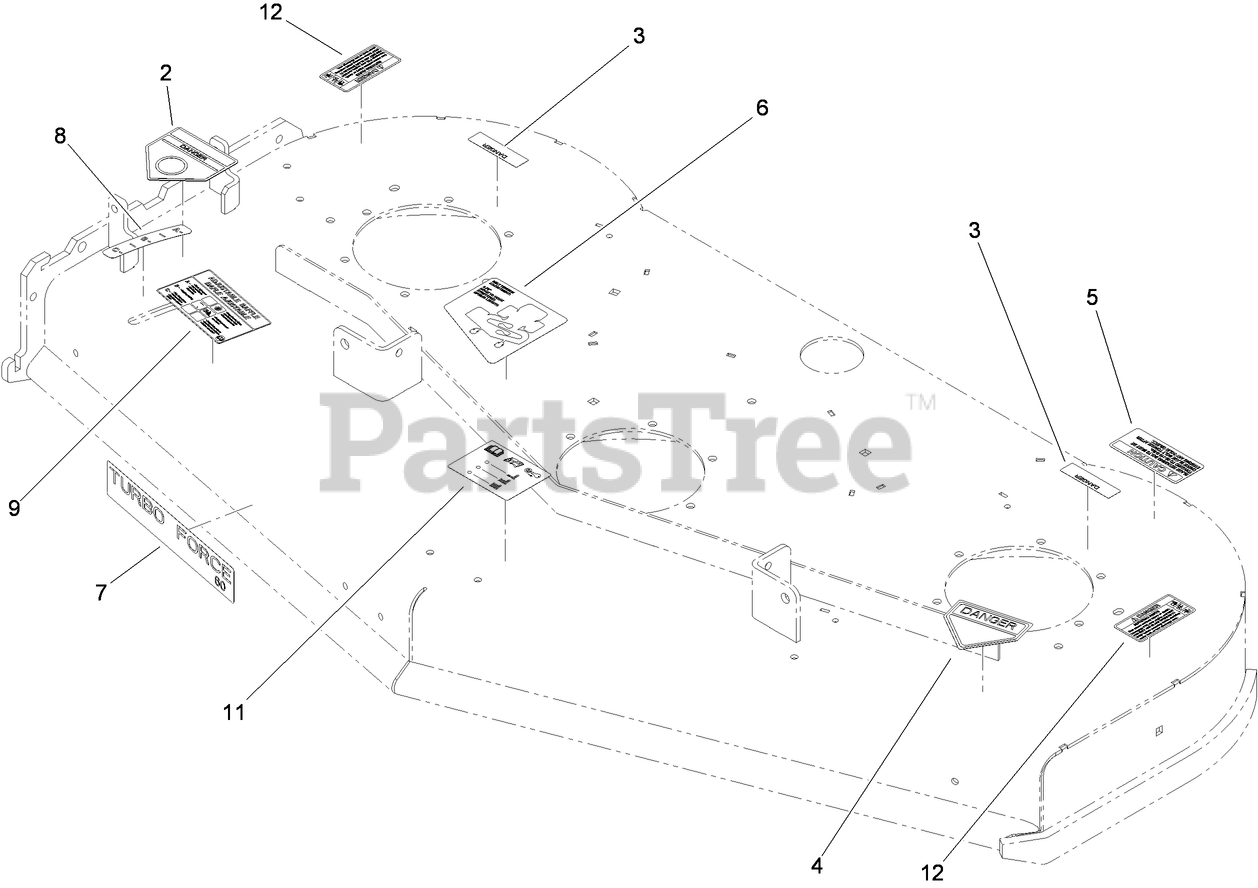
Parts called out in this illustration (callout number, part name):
2	DECAL-DANGER
3	DECAL-COVER, MISSING
4	DECAL-DANGER
5	DECAL-TORQUE
6	DECAL-TENSION, BELT
8	DECAL-SETTING, BAFFLE
9	DECAL-ADJUSTMENT, BAFFLE
11	DECAL-SCALP, ANTI
12	DECAL-ROTATING PARTS
